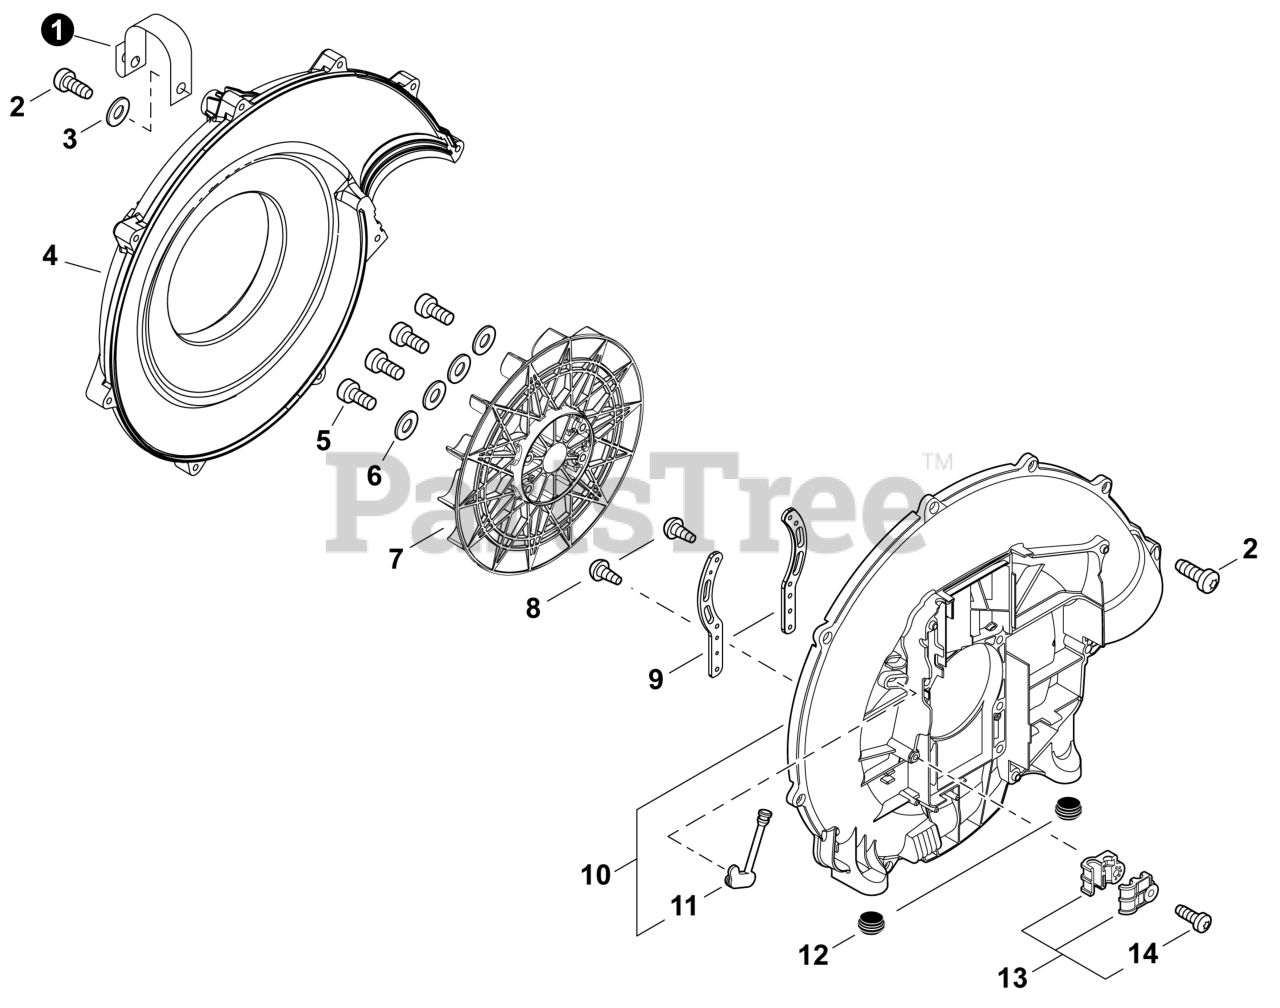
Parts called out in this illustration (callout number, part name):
1	STRAP, SAFETY 1.2x100
2	BOLT, TORX 5x20
3	WASHER 5.5x16x2T
4	COVER, FAN
5	BOLT, TORX 5x30
6	WASHER 5.5x16x2T
7	FAN, BLOWER
8	SCREW TAPPING 3x12
9	BRACKET, ENGINE
10	FAN CASE SET
11	GROMMET
12	CUSHION
13	CABLE HOLDER SET
14	BOLT, TORX 5x25
